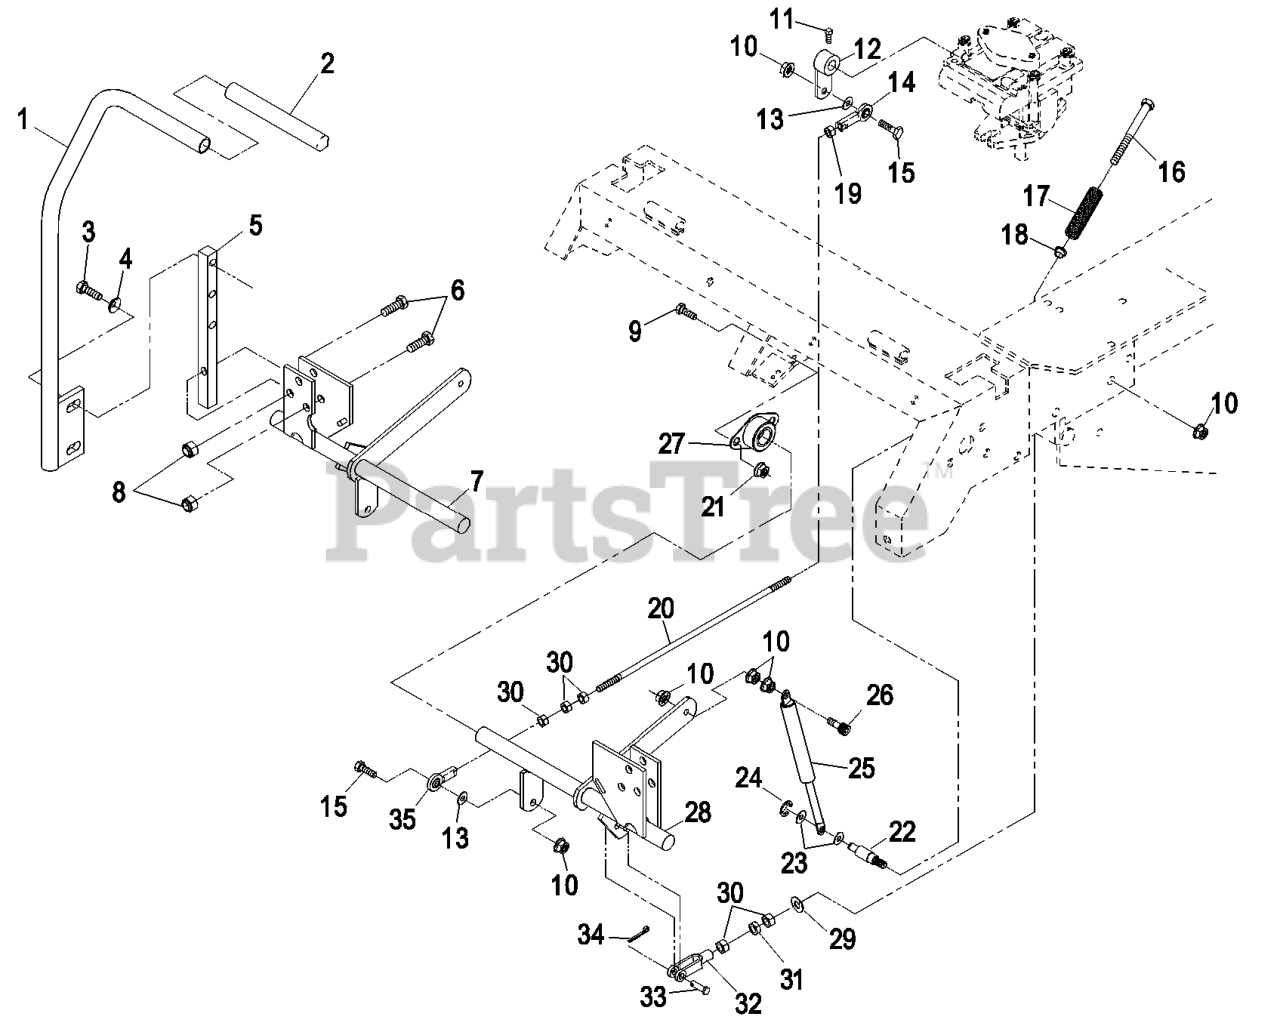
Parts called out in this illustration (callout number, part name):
1	RH LEVER ASM
2	GRIP-CONTROL, MOTION
3	SCREW-HH
4	WASHER-BELLEVILLE
5	ARM-SHAFT, CONTROL
6	SCREW-HH
8	NUT-LOCK, NI
9	SCREW-HH
11	SCREW-SET
13	WASHER-FLAT
14	BALLJOINT-LH
15	SCREW-HH
16	BOLT-RETURN, NEUTRAL
17	SPRING-RETURN, NEUTRAL
18	BUSHING-FLANGED
21	NUT-HHF, WHIZ
23	WASHER-PLAIN
24	RING-RETAINING, EXT
26	SCREW-HH
27	BEARING-FLANGE, SIDE
29	WASHER-FLAT
30	NUT-HEX
31	NUT-JAM
32	YOKE-ADJUSTABLE
33	PIN-CLEVIS
34	PIN-COTTER
35	BALLJOINT-RH
